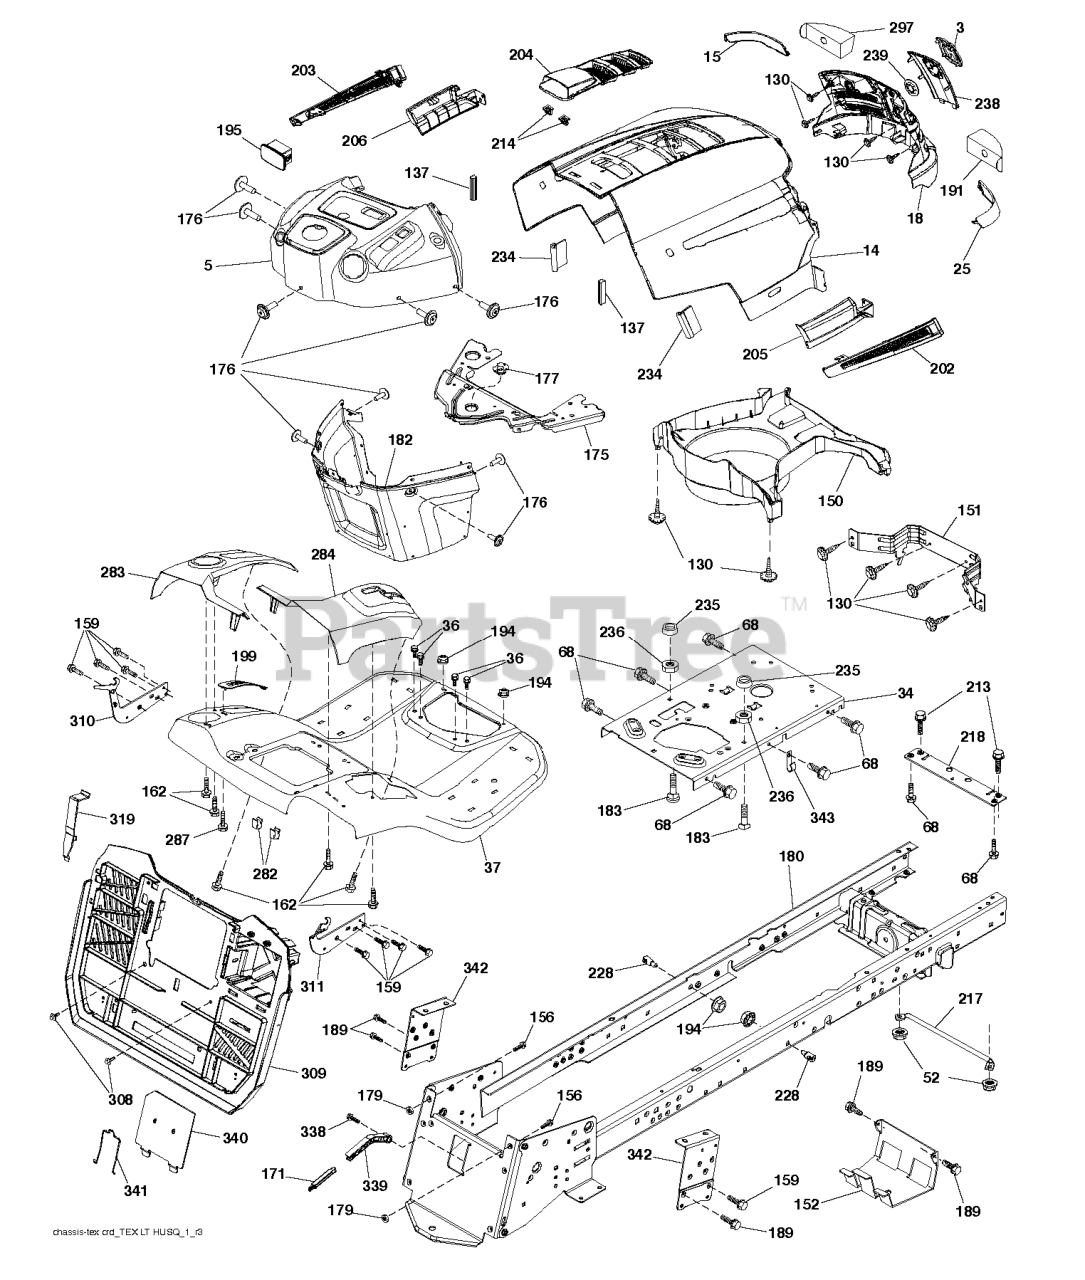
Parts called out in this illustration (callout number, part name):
3	RP LOGO
5	SUBASM.DASH.UPPER.W/BUMPER
14	HOOD.HUSQVARNA.LT.ORANGE
15	LENS.HUSQVARNA LT.RH
18	GRILLE.SVC.HUSQVARNA.GREY
25	LENS.HUSQVARNA LT.RH
34	PLATE.ENGINE.WELDED.CHASSIS
36	SCREW 5/16"
37	FENDER.TEX.SRD.CRD.BASE
52	LOCKNUT
68	Screw 5/16-18 x 1/2 Hex, Self Tapping 5/16-18 x 1/2
130	SCREW.#10 X 0.750.BOS
137	BUMPER DASH
151	BRACKET PIVOT
152	SHIELD.BROWNING.W/TEX
159	SCREW, 3/8-16X3/4
162	SCREW.HI-LO.CONSOLE
171	EXTENSION.BAGGER.FULL.
175	CROSSMEMBER
176	SCREW.#10-24X5/8.RN.QU
177	BUSHING STEERING
182	DASH.LOWER.PREDATOR LT
183	BOLT.5/16-18X1-1/4 FULL THD
189	SCREW
191	INSERT.REFLECTIVE.RH.
194	NUT LOCK HEX FLANGE 5/16-18
195	PLATE PLATE ENGINE
199	PLATE DECK LIFT
202	VENT.SIDE.HUSQVARNA.LT.RT
203	VENT.SIDE.HUSQVARNA.LT.LFT
204	SUBASM.TOP.VENT.HUSQ.LT
205	SKIRT.SIDE.HUSQVARNA.LT.RT
206	SKIRT.SIDE.HUSQVARNA.LT.LEFT
213	BOLT
214	CLIP.RETAINER.TINNER.
217	ROD.PIVOT.HOOD
218	X-PIECE.HOOD.STOP.NON/
228	STUD.FASTNER.W/ANTI-ROTATE
234	BUMPER.HOOD.TEX.HUSQVARNA
235	SPACER FENDER
236	NUT.CENTERLOCK.5/16-
238	TRIM.HUSQ LT.668
282	CLIP.RETAINER.CONSOLE.LT.HUSQ
283	CONSL.DECKLIFT.LH.SRD.TEX.CRD
284	CONSL.SHFT.PEDAL.RH.SRD.TEXCRD
287	SCREW 1/4X20
297	INSERT REFLECTIVE
308	BOLT.5/16-18UNCX3/4 W/SEMS.BLK
310	LH.ADJUST.HANGER.BRACKET.ASM
311	RH.ADJUST.HANGER.BRACKET.ASM
319	BRACKET.ACTUATOR.BAGGER.SRD
338	BOLT BOLT SHOULDER
339	LEVER.BAGGER.FULL.TEX.
340	DOOR.PNT.BATTERY.TRY.TEX.CRD.
341	LATCH
342	SUPPORT SUPPORT FENDER
343	CLIP CLIP
